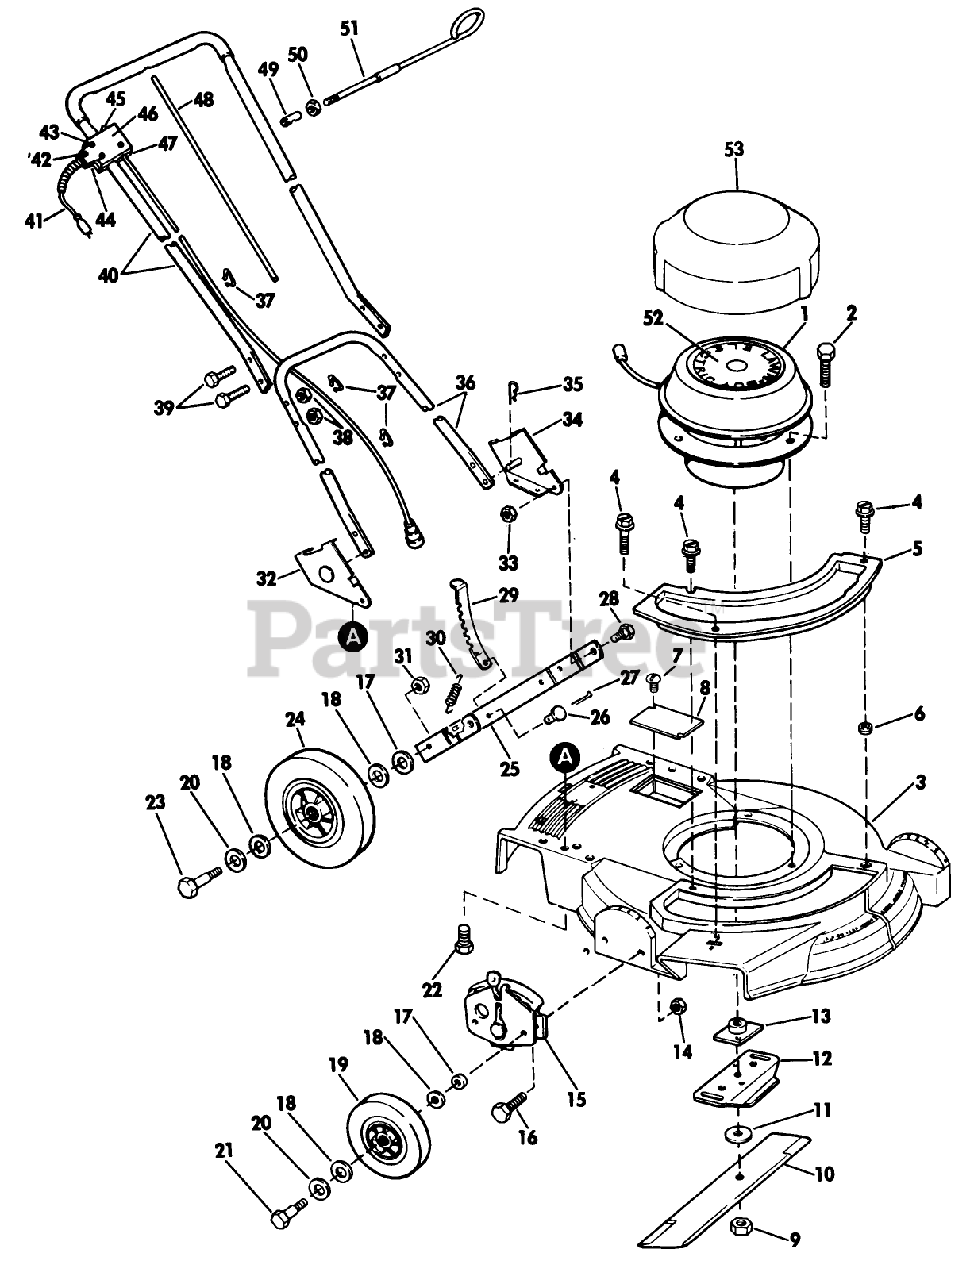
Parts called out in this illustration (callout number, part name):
4	SCREW SEMS TRM HEX HD
9	NUT-BLADE
13	PLATE AND COLLAR ASM
17	WASHER WROUGHT
21	BOLT WHEEL
28	BOLT-SHOULDER
30	SPRING N.A.S
31	LOCKNUT
35	HAIR PIN
42	Screw-Ground
